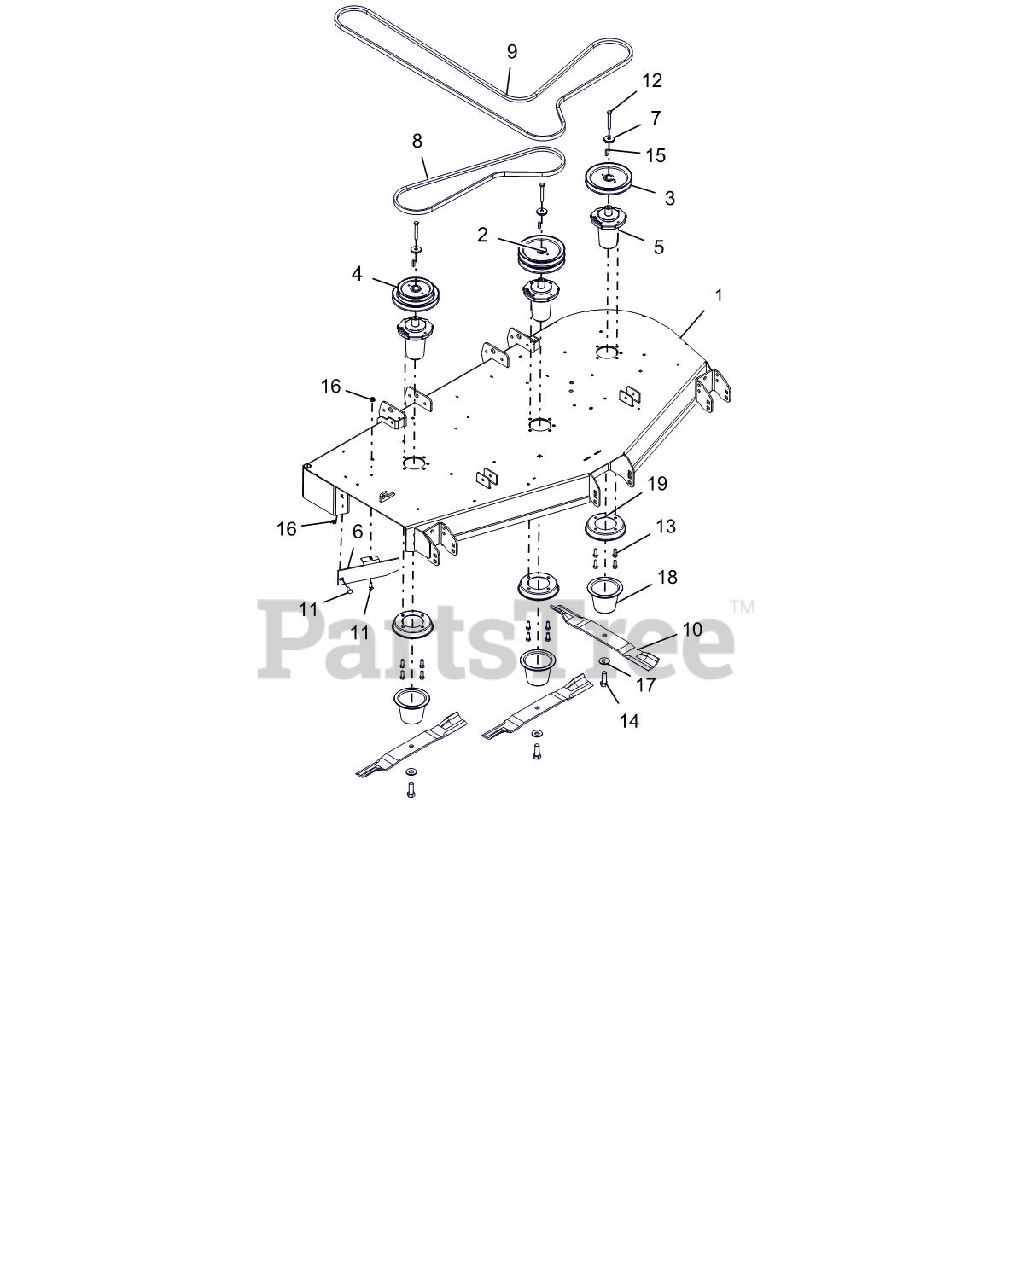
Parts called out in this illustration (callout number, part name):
1	DECK, PT60 W/SAFETY DECALS
2	PULLEY, DOUBLE-1"ID X 6.75"OD
3	PULLEY, V-1" ID X 6.75" OD
4	PULLEY, DBL-1"IDX6.75"&5.25"OD
5	ASM, MAINT FREE SPINDLE
6	60" DISCHARGE BAFFLE - RED
7	RETAINER, SHEAVE
8	V-BELT, B-COGGED
9	BELT, B-SECTION EPDM RAW EDGE
10	BLADE, MOWER (20.50")
11	@BLT-RDHDSQNK .31-18X1.00 G5YZ
12	BLT-HEX .38-16X2.75 GR8 YWZC
13	BLT-HEX .38-16X1.0 GR8 YZ EP30
14	BLT-HEX .62-18X1.75 GR8 YWZC
15	KEY, SQ .25X.25X1.00 RC 40-50
16	@NUT-LK-NYL-FLG .31-18 YWZC
17	WSHR-BLVL .669X1.535X.138
18	GUARD, SPINDLE LOWER
19	GUARD, SPINDLE TOP
